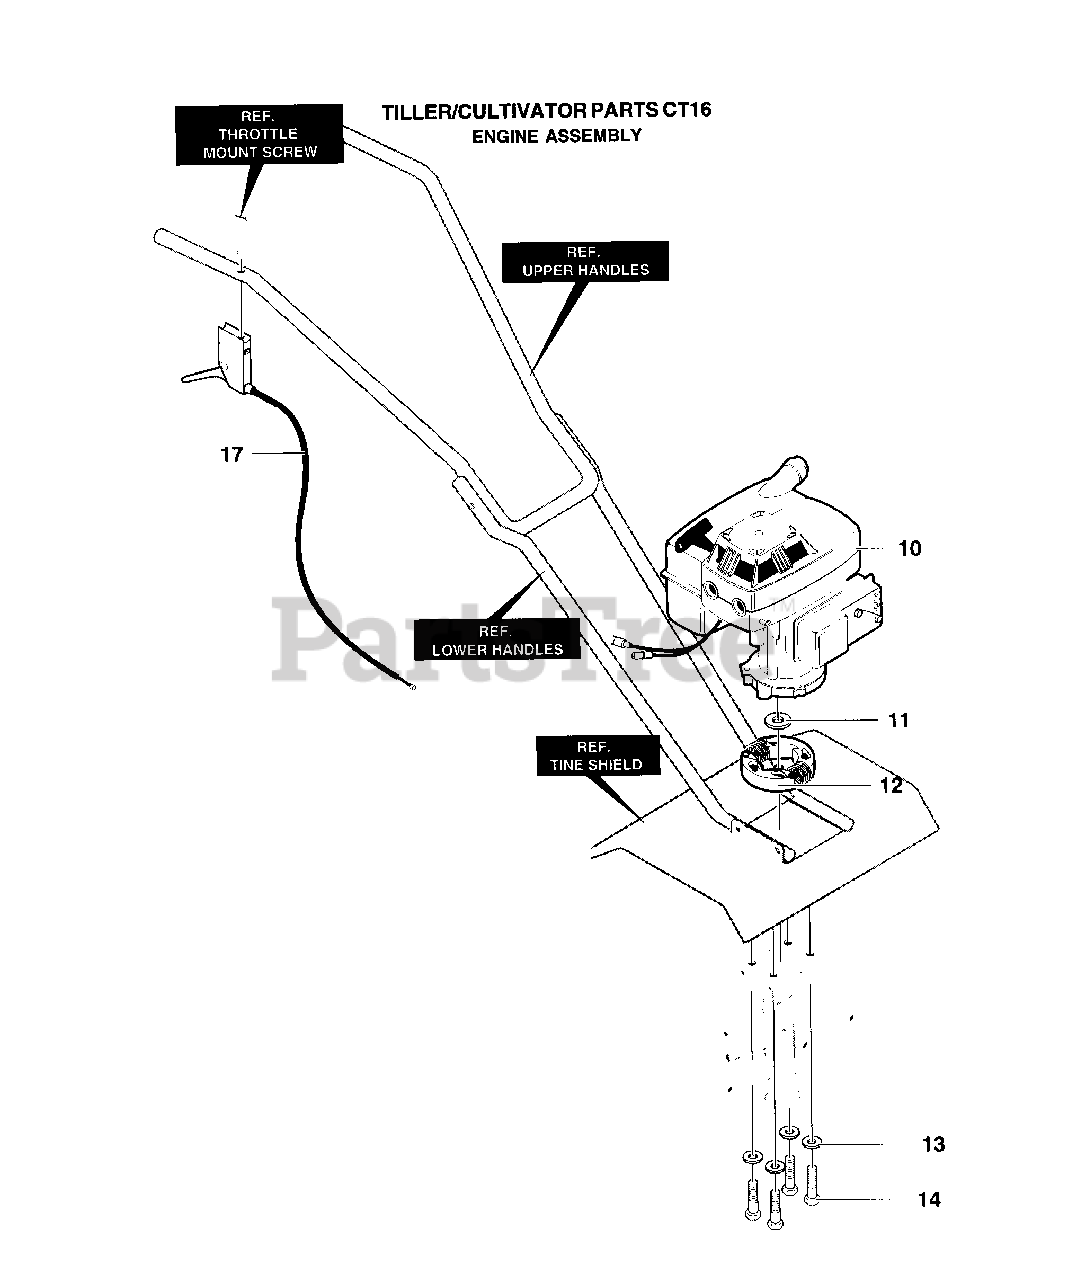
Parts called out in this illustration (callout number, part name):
11	WASHER, FLAT .378X1.25X.06
12	ROTOR (SMALLER DIA.)
13	WASHER, REGSPTLK.263X.49X.07
14	SCREW, 1/4-20X1.75 HHC
17	CABLE, THROTTLE, CULTIVATOR
